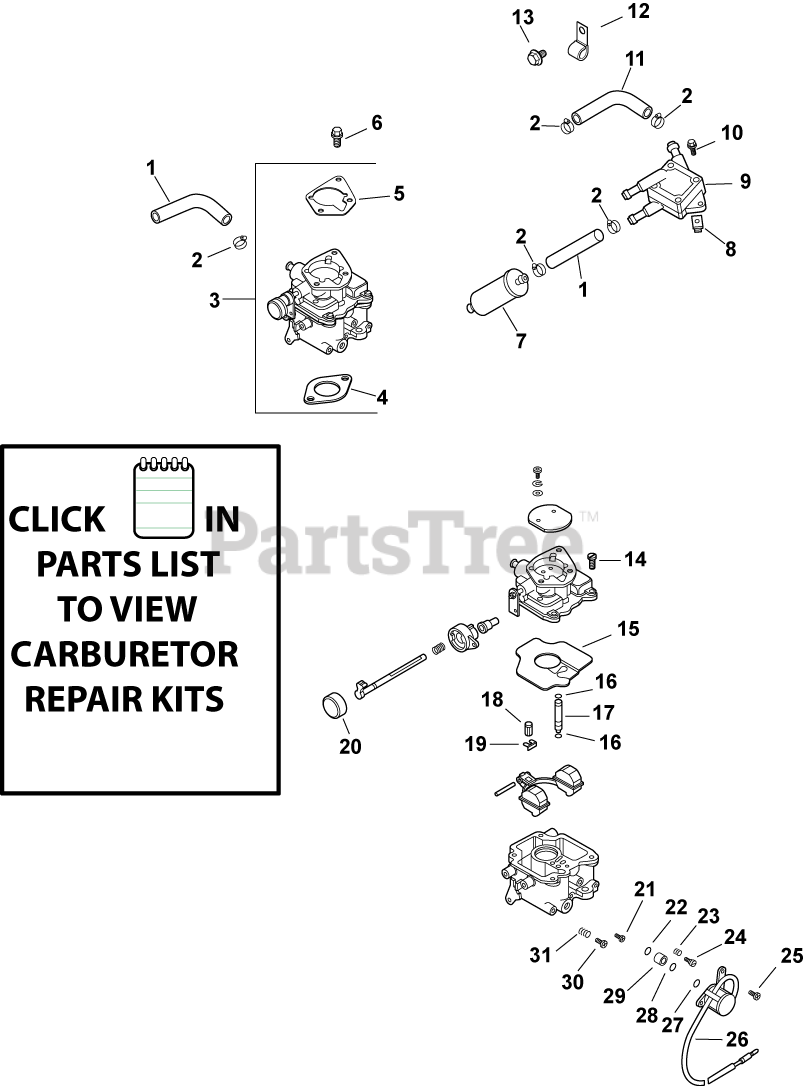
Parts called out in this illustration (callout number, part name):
1	HOSE,LW PERM.FUEL 24.00"-USE 25 111 81-S
2	CLAMP, HOSE (KM)-USE 25 237 31-S
3	KIT, CARBURETOR W/GASKETS KSF
4	GASKET, CARBURETOR
5	GASKET, AIR CLEANER BASE
6	SCREW, FLG M6X1.0X30
7	FILTER, FUEL
8	NUT, PLASTIC - BLACK
9	PUMP, FUEL
10	SCREW, TAP M6X1.7X18
11	LINE, FLEXIBLE FUEL 15 1/2"
12	CLIP, CABLE
13	SCREW, FLNG THD FRM M6X1.0X10 USE 25 086 406-S
14	SCREW, CARBURETOR BODY
15	GASKET, CARBURETOR BODY
16	O-RING, SLOW JET
17	JET, SLOW
18	VALVE, INLET NEEDLE
19	CLIP, INLET NEEDLE VALVE
20	CAP, CHOKE LEVER
21	JET, MAIN
22	O-RING, SOLENOID
23	SPRING, IDLE NEEDLE
24	NEEDLE, IDLE
25	SCREW, SOLENOID
26	SOLENOID ASSEMBLY
27	O-RING, SOLENOID
28	O-RING, SOLENOID
29	SEAT, SOLENOID
30	SCREW, IDLE
31	SPRING, IDLE SPEED ADJ SCREW
